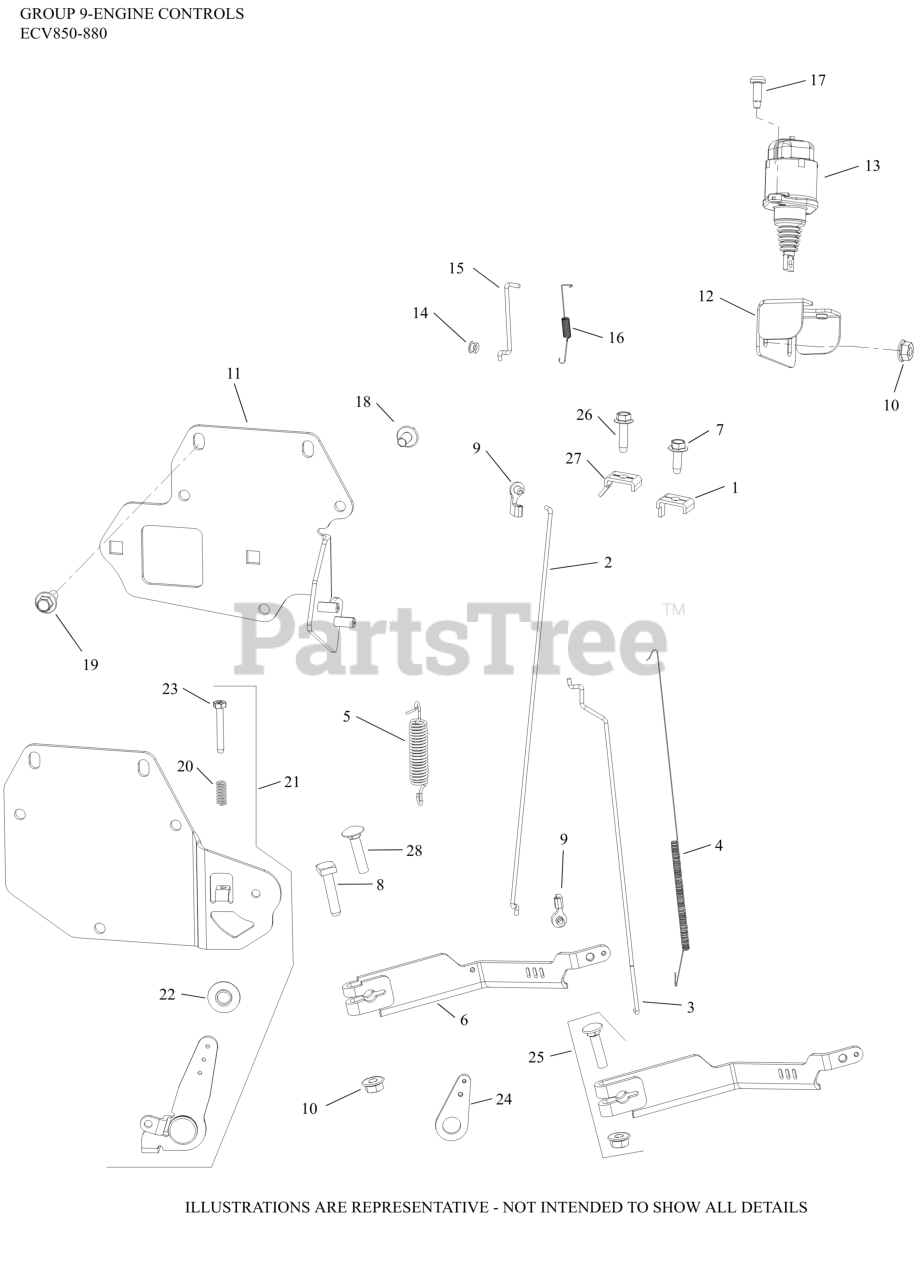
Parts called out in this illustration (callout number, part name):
1	CLAMP, CABLE-(#2523753S)
2	LINKAGE, SPEED CONTROL
3	LINKAGE, THROTTLE
4	SPRING, LINKAGE
5	SPRING, GOVERNOR
6	ARM, GOVERNOR-(#1918605S)
7	SCREW, THREAD FORMING
8	SCREW, T HEAD
9	BUSHING, THROTTLE LINKAGE
18	SCREW, FLG M6X1.0X12
20	SPRING, SPEED CONTROL (SHORT)
21	BRACKET, ASSEMBLY THROTTLE CONTROL
22	WASHER, NYLON SHOULDER
23	KIT, IDLE ADJ SCREW & SPRING
